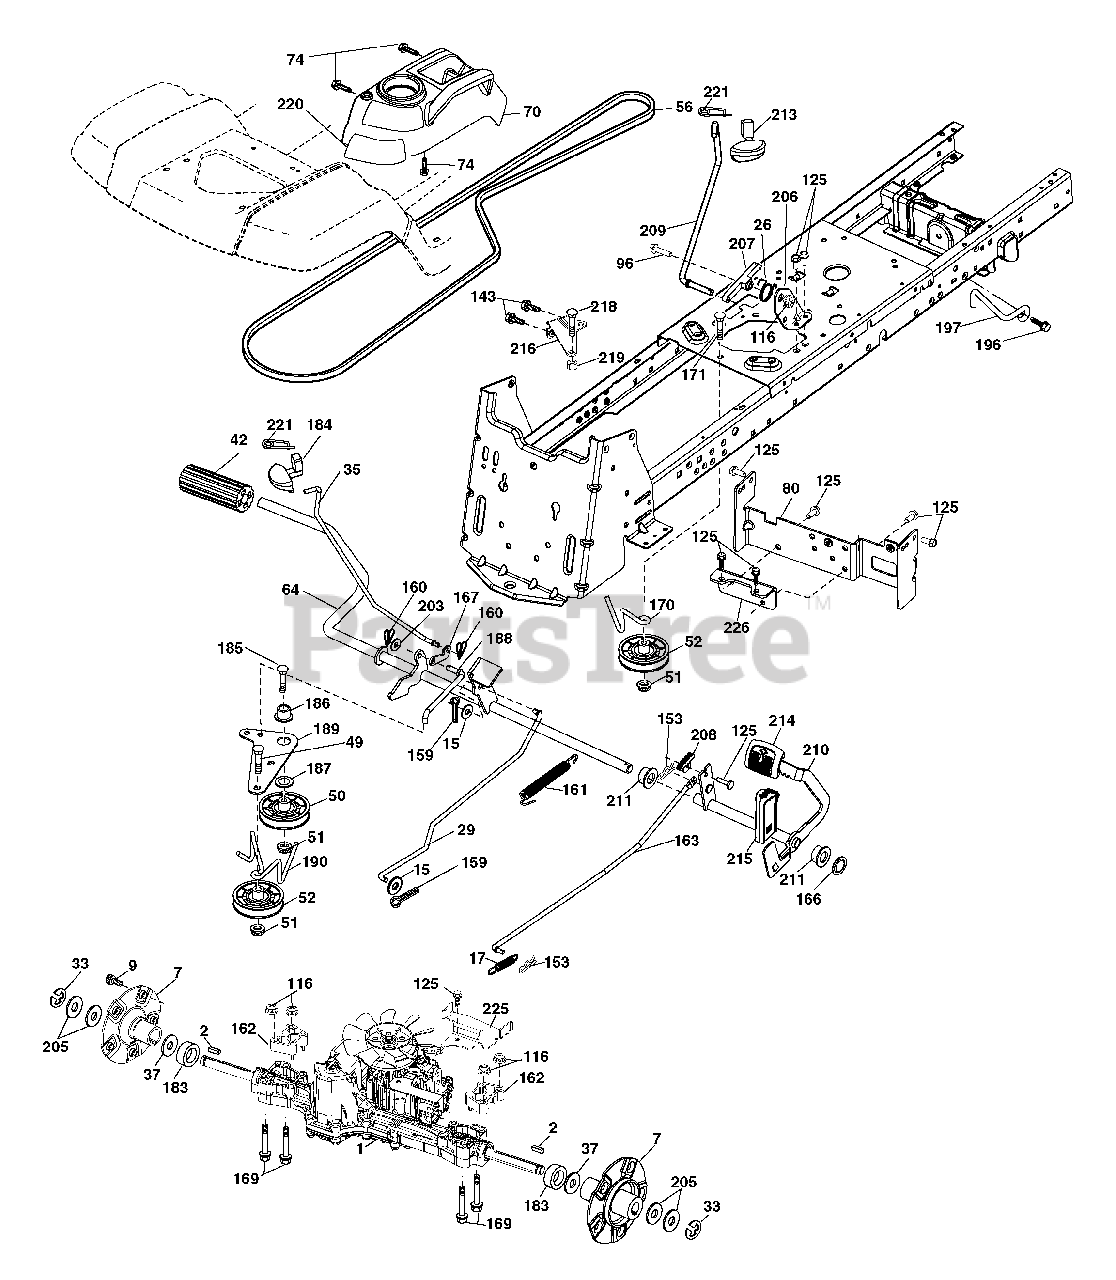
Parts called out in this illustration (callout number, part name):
2	Key 1/4 x 2.5
7	Hub Asm. Wheel
9	Bolt Hub Wheel
15	Washer 13/32 x 13/16 x 16 Ga.
17	Spring, Brake
26	Spring Return Cruise
29	Rod, Brake
35	Rod, Brake, Park
42	Cover, Foot Pedal
50	Pulley Idler Flat
51	Lock Nut 3/8-16
52	Idler V-Groove 910" Offset
56	V-Belt, Drive
64	Shaft Asm. Pedal Brake Control
70	Control Asm.
74	Screw 1/4 x 1/2
80	Bracket Strap Torque
96	Bolt Fin Hex 5/16-18 unc x 1.25
116	Nut Lock Hex Flange 5/16-18
125	Screw 5/16-18 x 3/4
143	Screw Thdrol 5/16-18 x 1/2
153	Retainer Spring
159	Pin Cotter 1/8 x 3/4
160	Retainer Clip
161	Spring, Return, Clutch
162	Spacer Transaxle
163	Rod Pedal Control
166	Nut Push .625
167	Latch Brake Parking
169	Bolt Hex Flghd 5/16-18 x 3.75
170	Keeper Belt Centerspan
171	Bolt RDHD SQNK 3/8-16UNC x 2
183	Spacer Split
184	Handle Parking Brake
185	Bolt Rdhd Sqnk 3/8-16 x 2-1/2
186	Spacer Retainer
187	Washer
188	Link Clutch Ground Drive
189	Bellcrank Ground Drive
190	Keeper Bellcrank Ground Drive
196	Screw 3/8-16 x 1
197	Bracket Clutch Anti-Rotation
203	Washer 11/32 x 11/16 x 16 Ga.
206	Bracket Mount Latch Cruise
207	Latch Control Cruise
208	Gear Sector Control Cruise
209	Rod Control Cruise
210	Rocker Asm. Pedal Control
211	Bearing Nylon
213	Knob Control Cruise
214	Pedal Forward
215	Pedal Reverse
216	Bracket Pulley Idler
218	Bolt Fin Hex 5/16-18 unc x 1-1/4
219	Spacer Fender
220	Reflector RH
221	Retainer Spring Clip Handle
222	Washer 21/32 x 1-1/4 x 10 Ga.
225	Keeper Belt Trans.
226	Bracket Mount Touque
